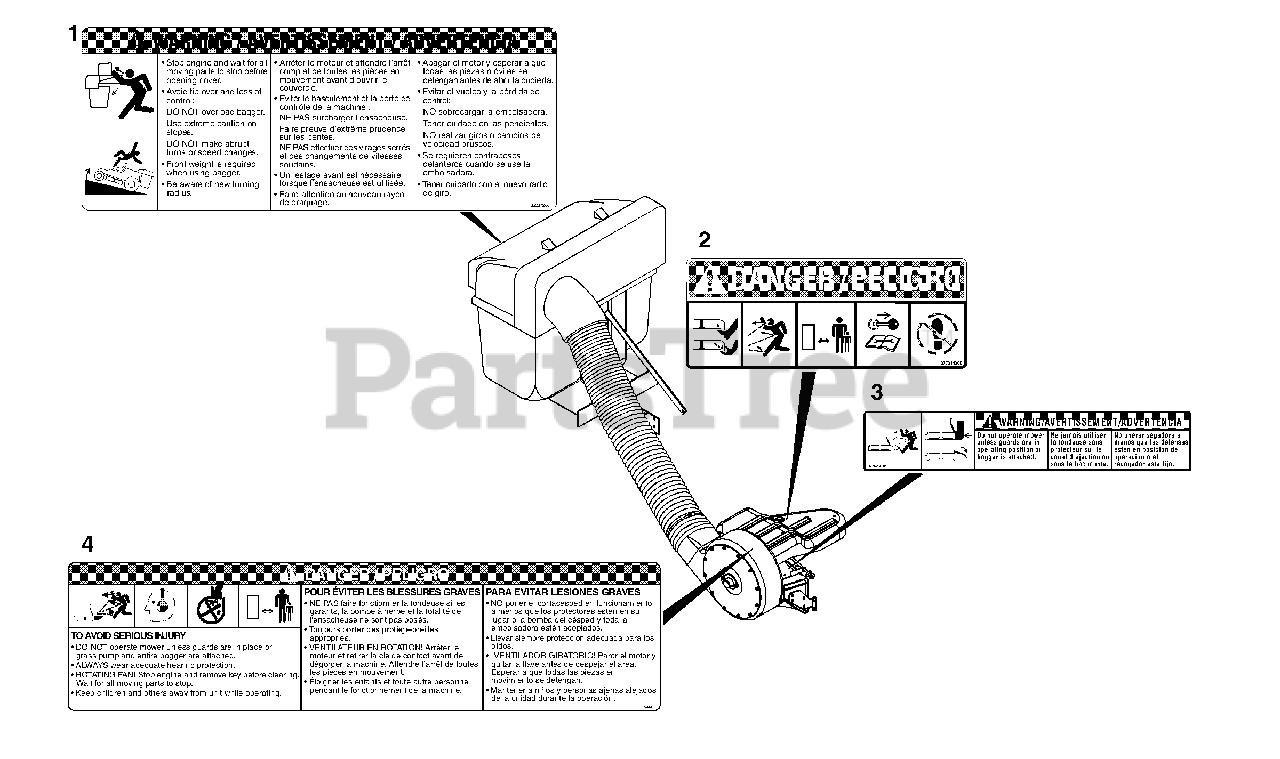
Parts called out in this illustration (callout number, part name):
1	DECAL-BAGGER HOOD EZR
2	DECAL, MOWER PAN DANGER
3	DECAL, WARNING
4	DECAL-CAUTION, GRASS PUMP
